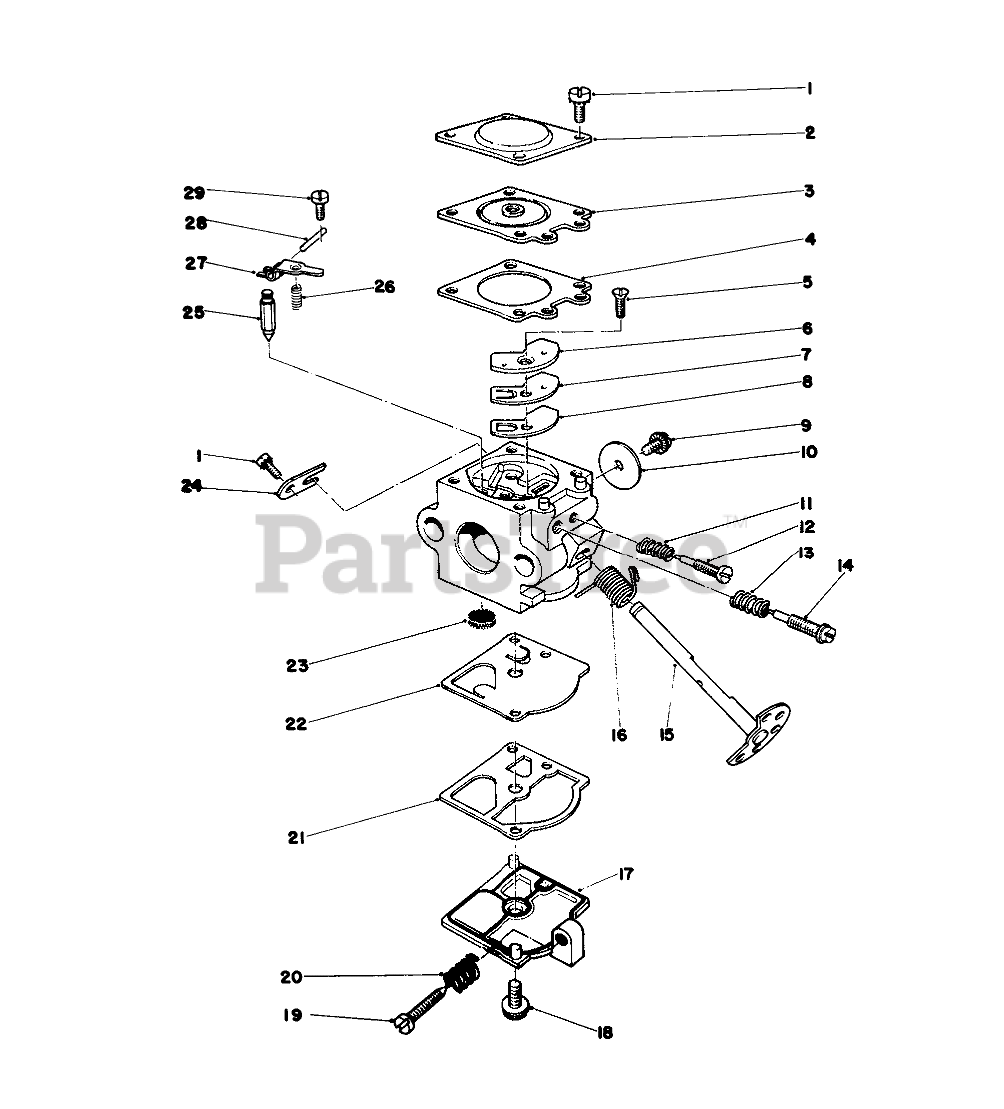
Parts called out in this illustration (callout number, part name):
1	Screw
2	Cover, Diaphragm
3	METERING DIAPHRAGM
4	Gasket, Diaphragm
5	Screw-Circuit Plate
6	Plate, Circuit
7	Diaphragm Circuit Plate
8	Gasket-Circuit Plate
9	Screw
10	Valve Throttle
11	Spring, Needle
12	Needle, Idle
13	Spring, HS Needle
14	HIGH SPEED NEEDLE
15	Shaft, Throttle
16	Spring, Throttle Return
17	Cover, Fuel Pump
18	Screw
19	Screw, Idle Adjustment
20	Spring, Idle Screw
21	PUMP GASKET
22	Diaphragm Fuel Pump
23	Screen Inlet
24	Clip Throttle Shaft
25	INLET NEEDLE VALVE
26	Spring, Lever
27	Lever Metering
28	Metering Lever Pin
29	Screw-Metering Pin
